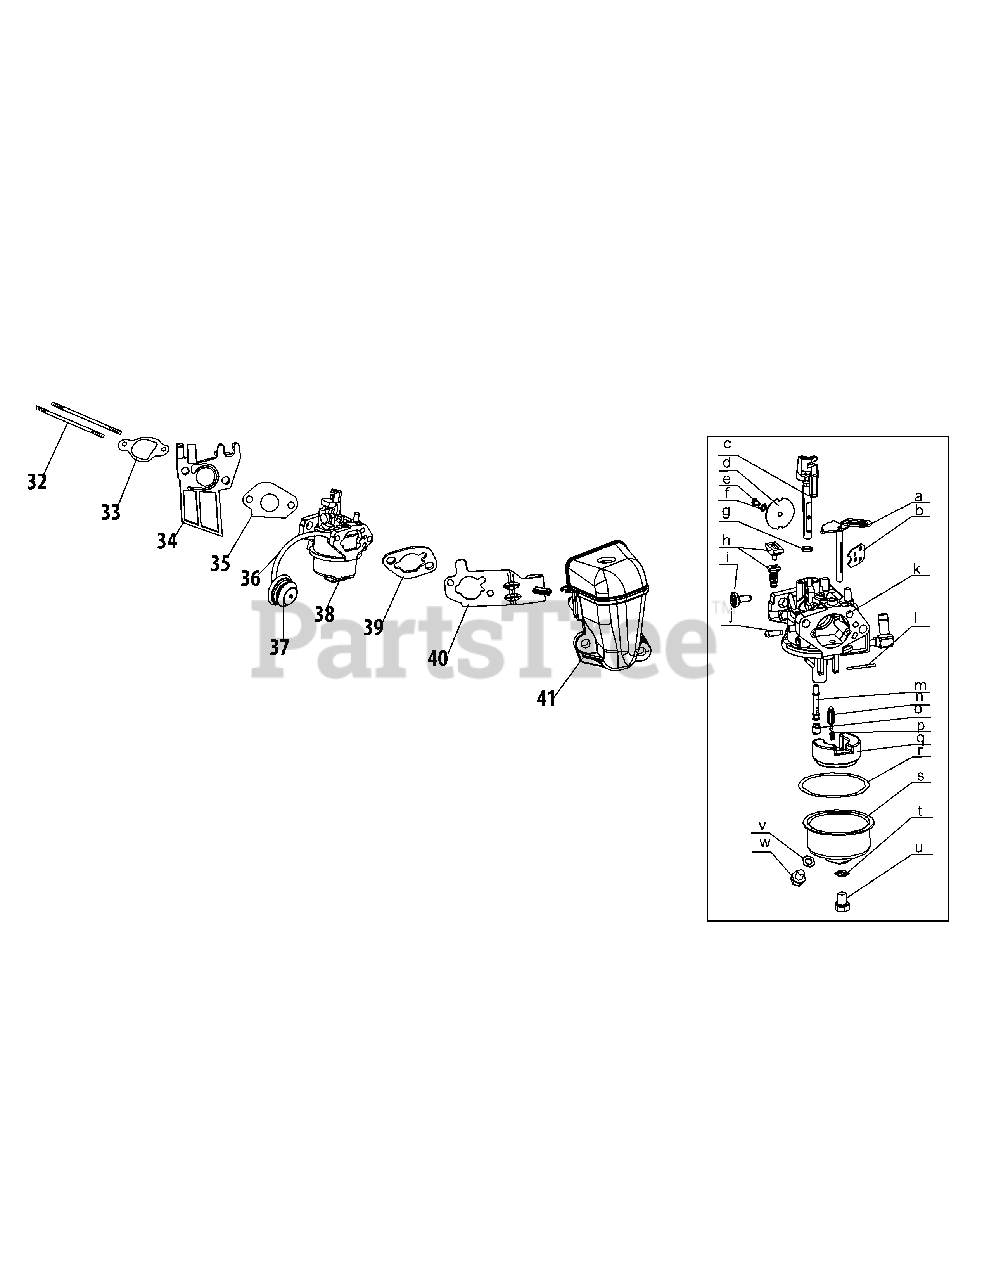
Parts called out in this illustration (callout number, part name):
32	Stud M6×92
33	Gasket, Carburetor Insulator
34	Insulator, Carburetor
35	Carburetor Gasket
36	Fuel Hose 3.2×6.5×150
38	Carburetor
39	Air Filter Gasket
40	Choke Controler Assy
41	Heater Box
